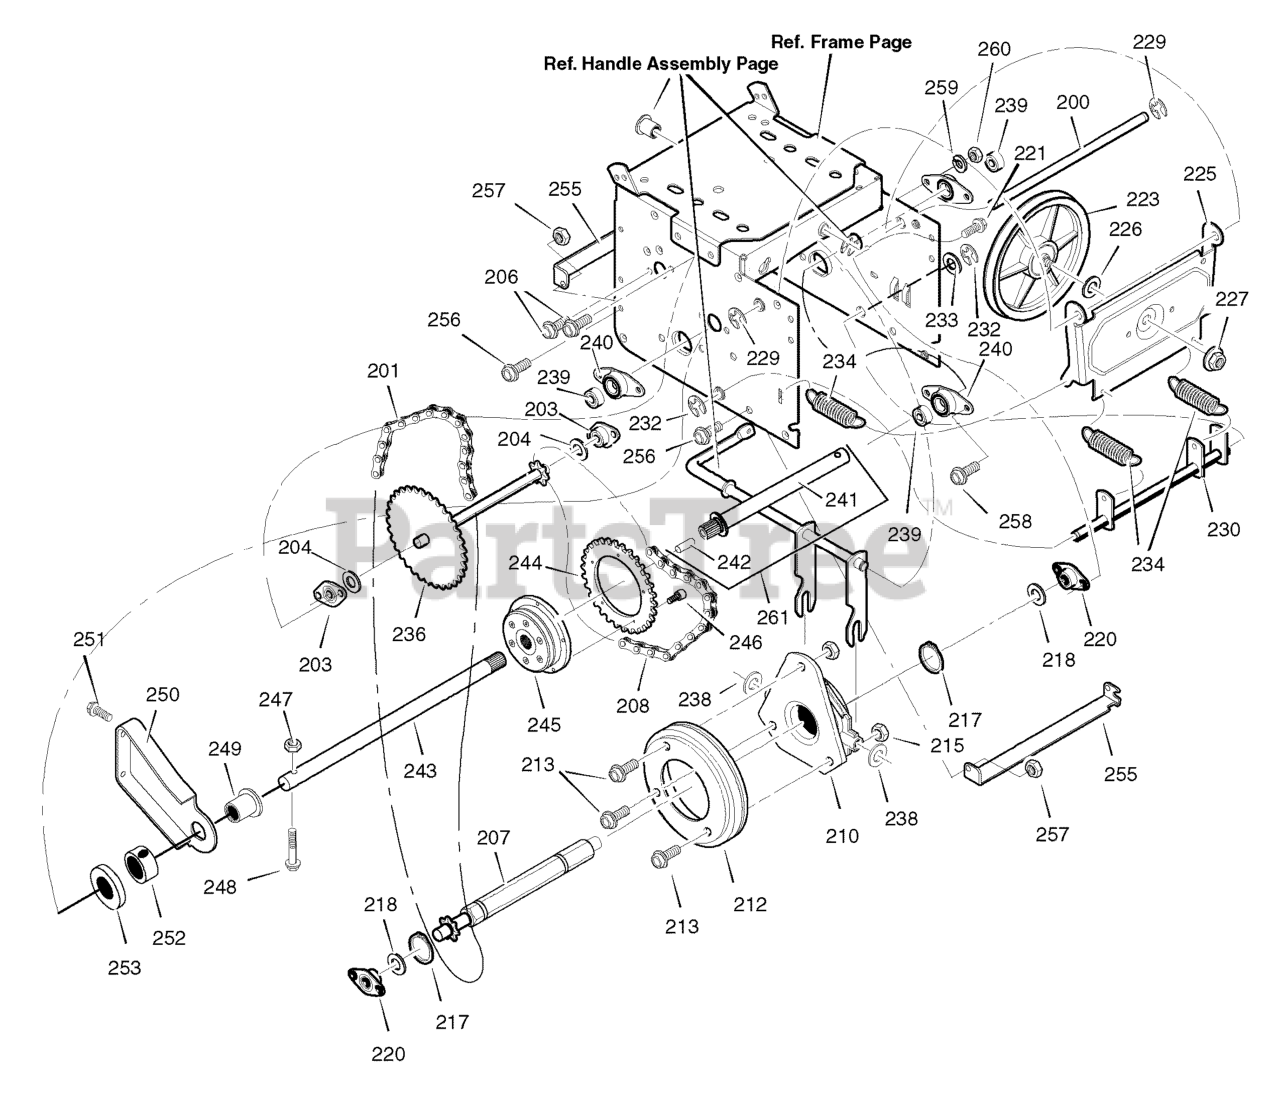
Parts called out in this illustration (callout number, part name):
200	LF AXLE, SWING PLATE YZ
201	CHAIN, ROLLER #420 X 19.00
203	BEARING AND RETAINER, ASSEMBLY
206	SCREW, TAP 5/16-18 X 0.5
207	HEX SHAFT ASSEMBLY
208	CHAIN, ROLLER #420 X 18.00 LG
210	BEARING, TRUNION CLUTCH R
212	WHEEL, FRICTION DISC
215	NUT, KEPS HEX 1/4-20
217	RING, RETEXT
220	BEARING AND RETAINER ASSEMBLY
221	SCREW, TAP 5/16-18 X 0.5
223	FRICTION PULLY
225	LF PLATE, SWINGING YZ
226	SPACER, FRICTION PULLEY
227	NUT, FLANGE LOCK 3/8-24
229	RETAINER, RING
230	ASSEMBLY, SPRING LINK STEERABLE
232	RETAINER, RING
234	SPRING, EXTENSION
236	SPROCKET SET 33T/7
238	WASHER, FLAT
239	BEARING, BALL
240	RETAINER, BEARING
241	AXLE, LEFT
242	PIN, AXLE
243	AXLE AND BUSHING, RIGHT
244	SPROCKET
245	CLUTCH, AUTO LOCK
247	NUT
249	BEARING, AXLE
250	BRACKET, AXLE SUPPORT
251	SCREW
252	COLLAR, LOCKING
255	BRACKET, SUPPORT
257	NUT
258	BOLT
259	WASHER
260	NUT
261	AXLE WASHER PIN ASSEMBLY
